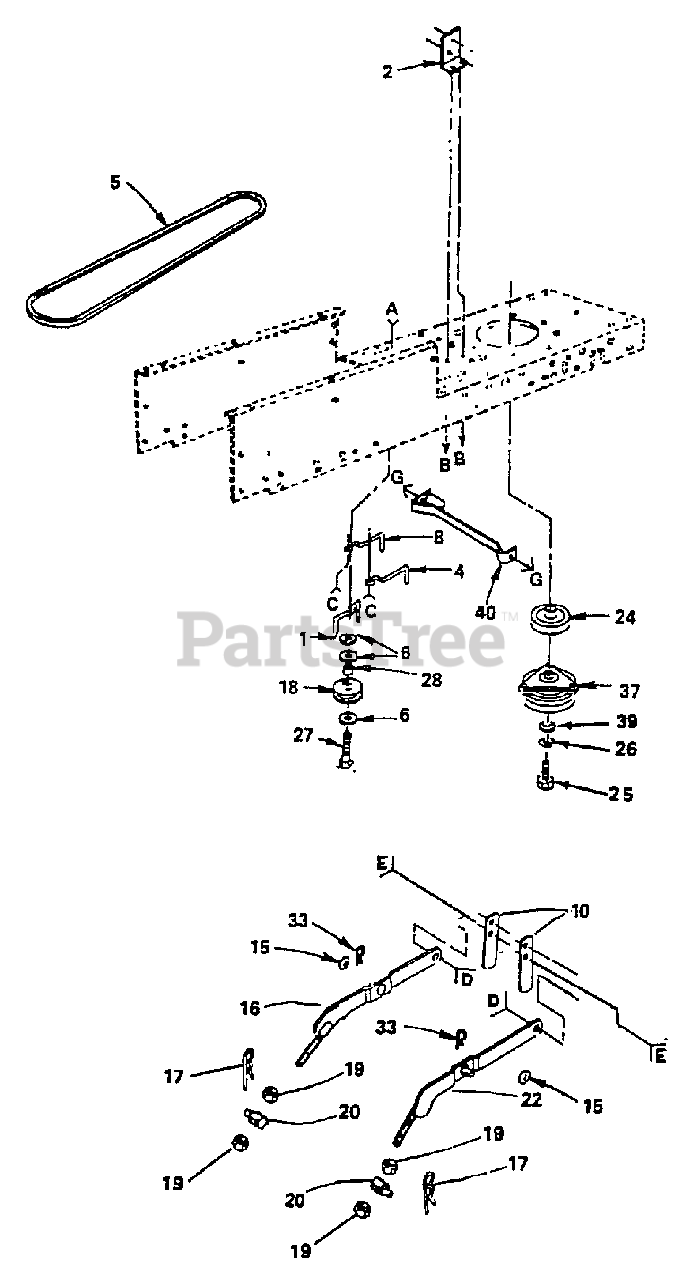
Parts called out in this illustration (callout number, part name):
1	Belt, Retainer
2	Bracket, Switch
4	Keeper, Belt, Engine
5	V-Belt, Drive
6	Washer 13/32 x 13/16 x 16 Gauge
8	Keeper, Belt, Engine
10	Upstop, Mower
15	Washer 17/32 x 15/16 x 16 Gauge
16	Arm Assembly, Suspension, L.H.
17	Spring, Retainer
18	Idler, Flat
19	Nut, Hex 1/2-13
20	Trunnion, Lift Lower
22	Arm Assembly, Suspension, R.H.
24	Pulley, Engine
25	Bolt, Hex 7/16-20 x 4 Grade B
26	Washer, Lock 7/16
27	Bolt, Hex 3/8-16 x 2-3/4
33	Spring, Retainer
37	Clutch, Electric
39	Washer 1-1/2 x 15/32 x 1/4
40	Locator, Clutch
